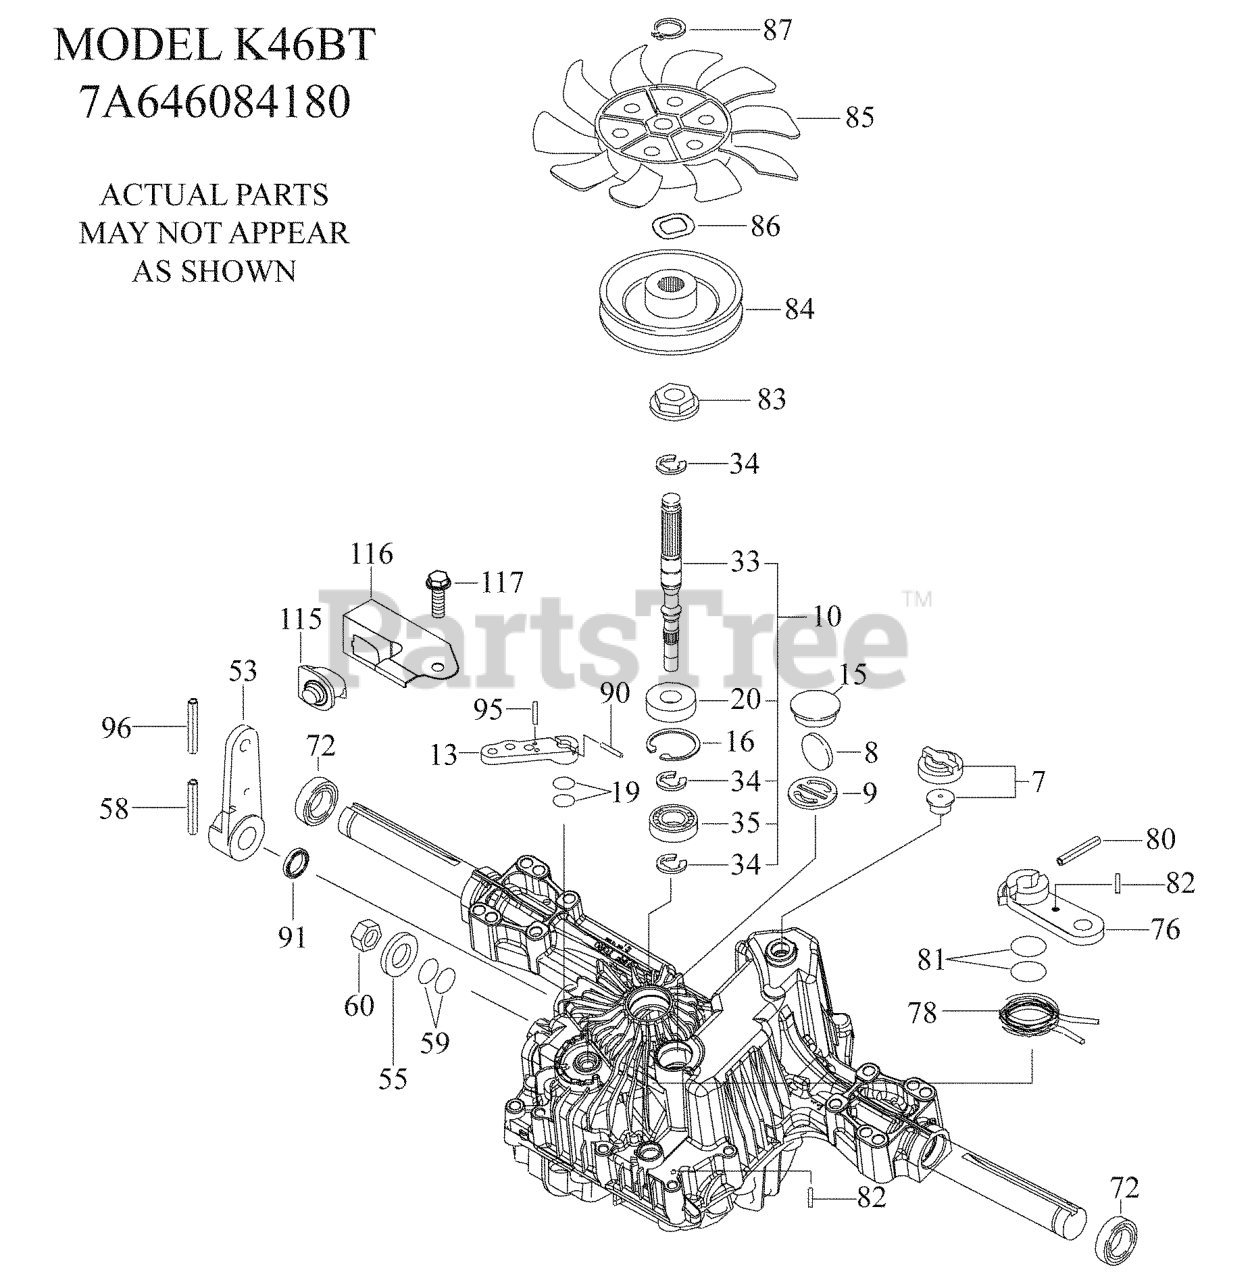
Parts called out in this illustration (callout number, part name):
7	VENT
8	MAGNET
9	Magnet Holder
10	Pump Shaft/Bearing Kit
13	LEVER
15	Sealing Cap 30
16	Snap Ring C 35
19	O-RING
20	SEAL
33	Pump Shaft
35	Bearing 6202c3
53	LEVER
58	Roll Pin 6 * 40
59	O-Ring 1a P14
72	SEAL.19, 19216334280
76	Brake Lever
78	SPRING
80	SPRING
81	O-RING
82	PEN
83	SPINE COLLAR
84	PULLEY
85	Fan, Black
86	WASHER
87	RING
90	PEN
91	SEAL
95	DECAL
96	PEN
115	Switch 6440-11 Delta
116	Switch Bracket
117	Tapping Screw 8 * 20
